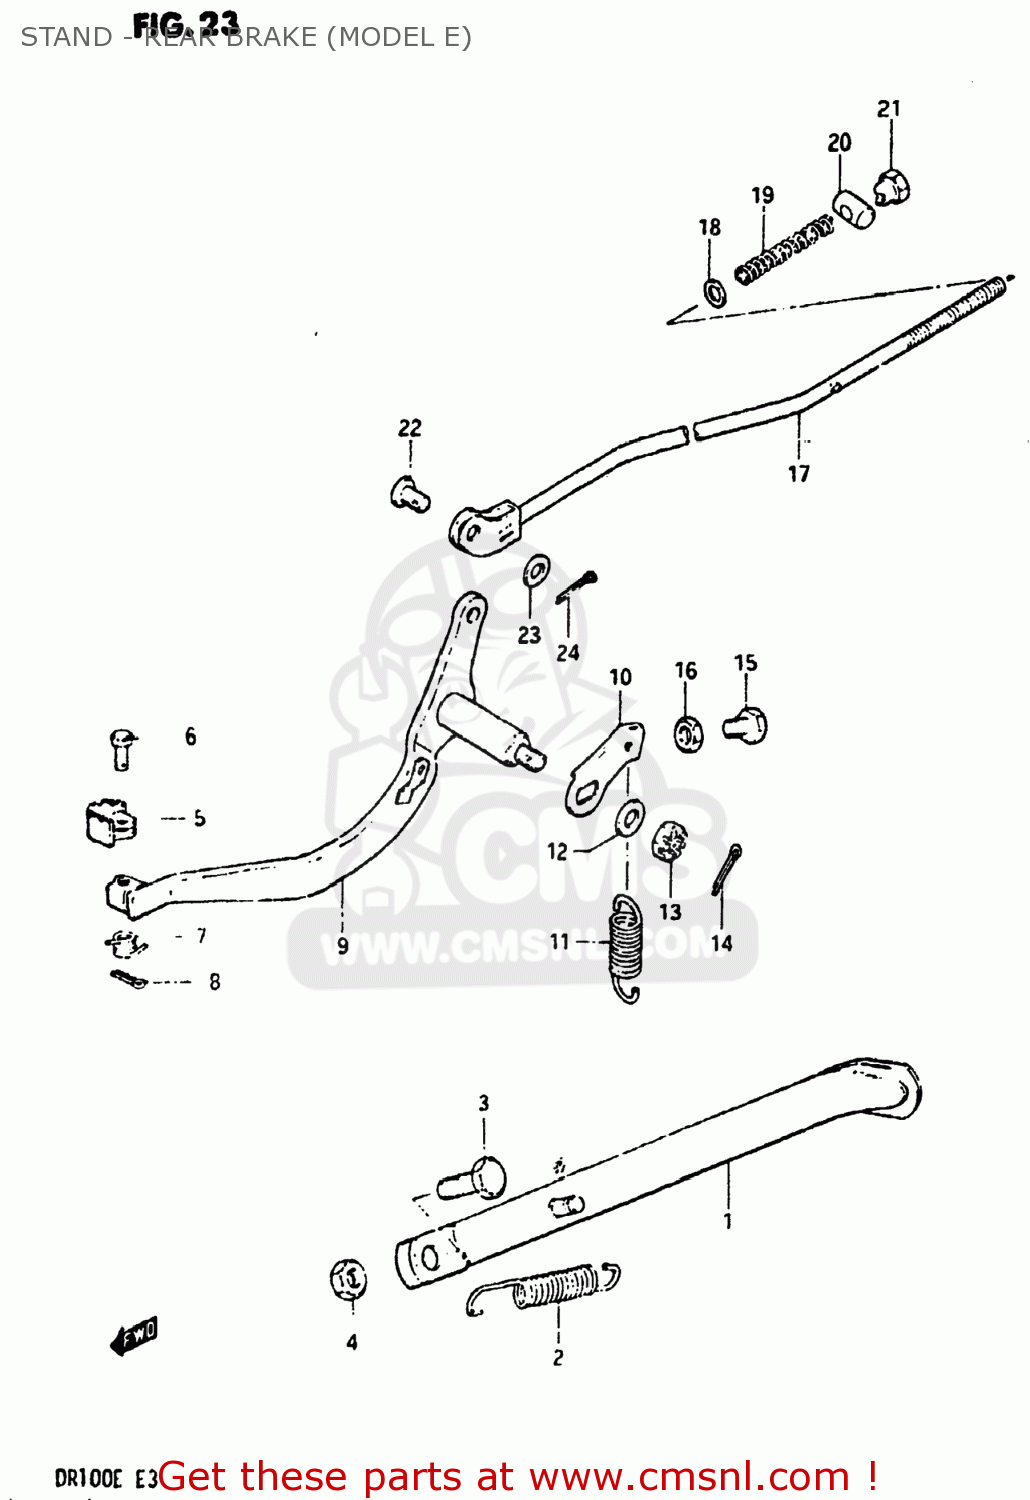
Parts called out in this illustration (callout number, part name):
1	STAND,SIDE
2	SPRING
3	BOLT(10X30)
4	NUT
5	PEDAL,BRAKE
6	PIN
7	SPRING
8	PIN
9	ARM,BRAKE PEDAL
10	ARM,BRAKE RETURN SPRING
11	SPRING
12	WASHER
13	NUT 8MM
14	PIN 20X20
16	NUT
17	ROD ASSEMBLY,REAR BRAKE
18	WASHER
19	SPRING
20	PIN(11X18)
21	NUT (6MM)
22	PIN
23	WASHER
24	PIN 20X20
